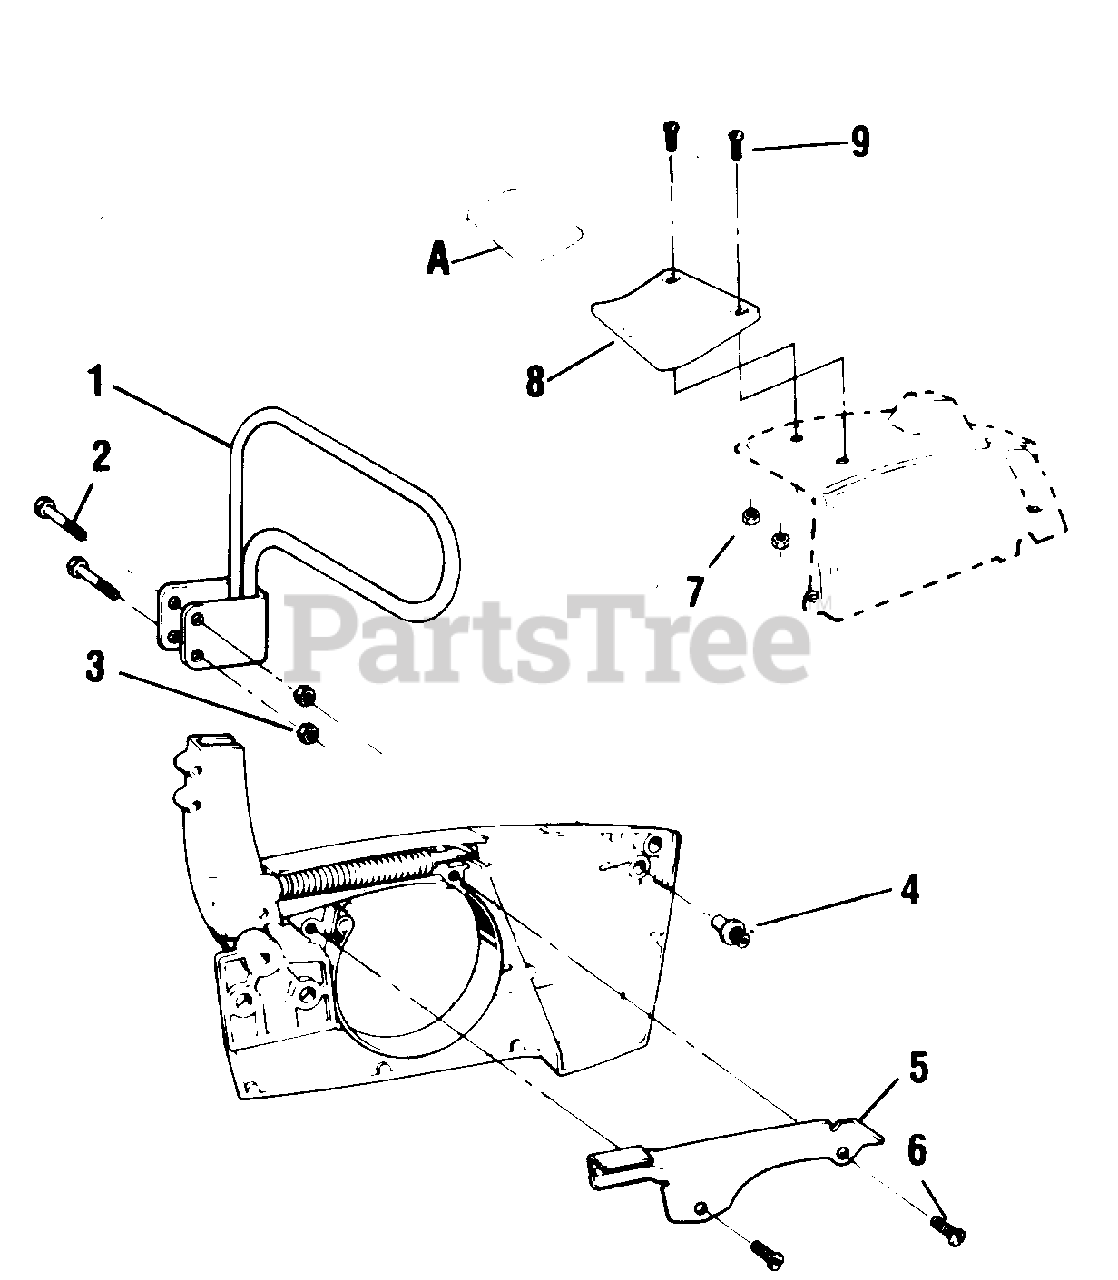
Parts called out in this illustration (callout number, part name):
1	Ass'y - Handguard
2	Screw - 10 - 24 Hex Hd.
3	Locknut - 10 - 24
4	Bar Clamp Guide Stud
5	Bracket - Brake Band
6	Screw - 10 - 24 x 7/16 Taptite Hex Hd.
7	Nut - Heat Shield
8	Shield - Heat
9	Screw - Heat Shield 10 - 24 #1/2 Pan Hd.
10	Bushing Guide
A	Decal - Instructions
